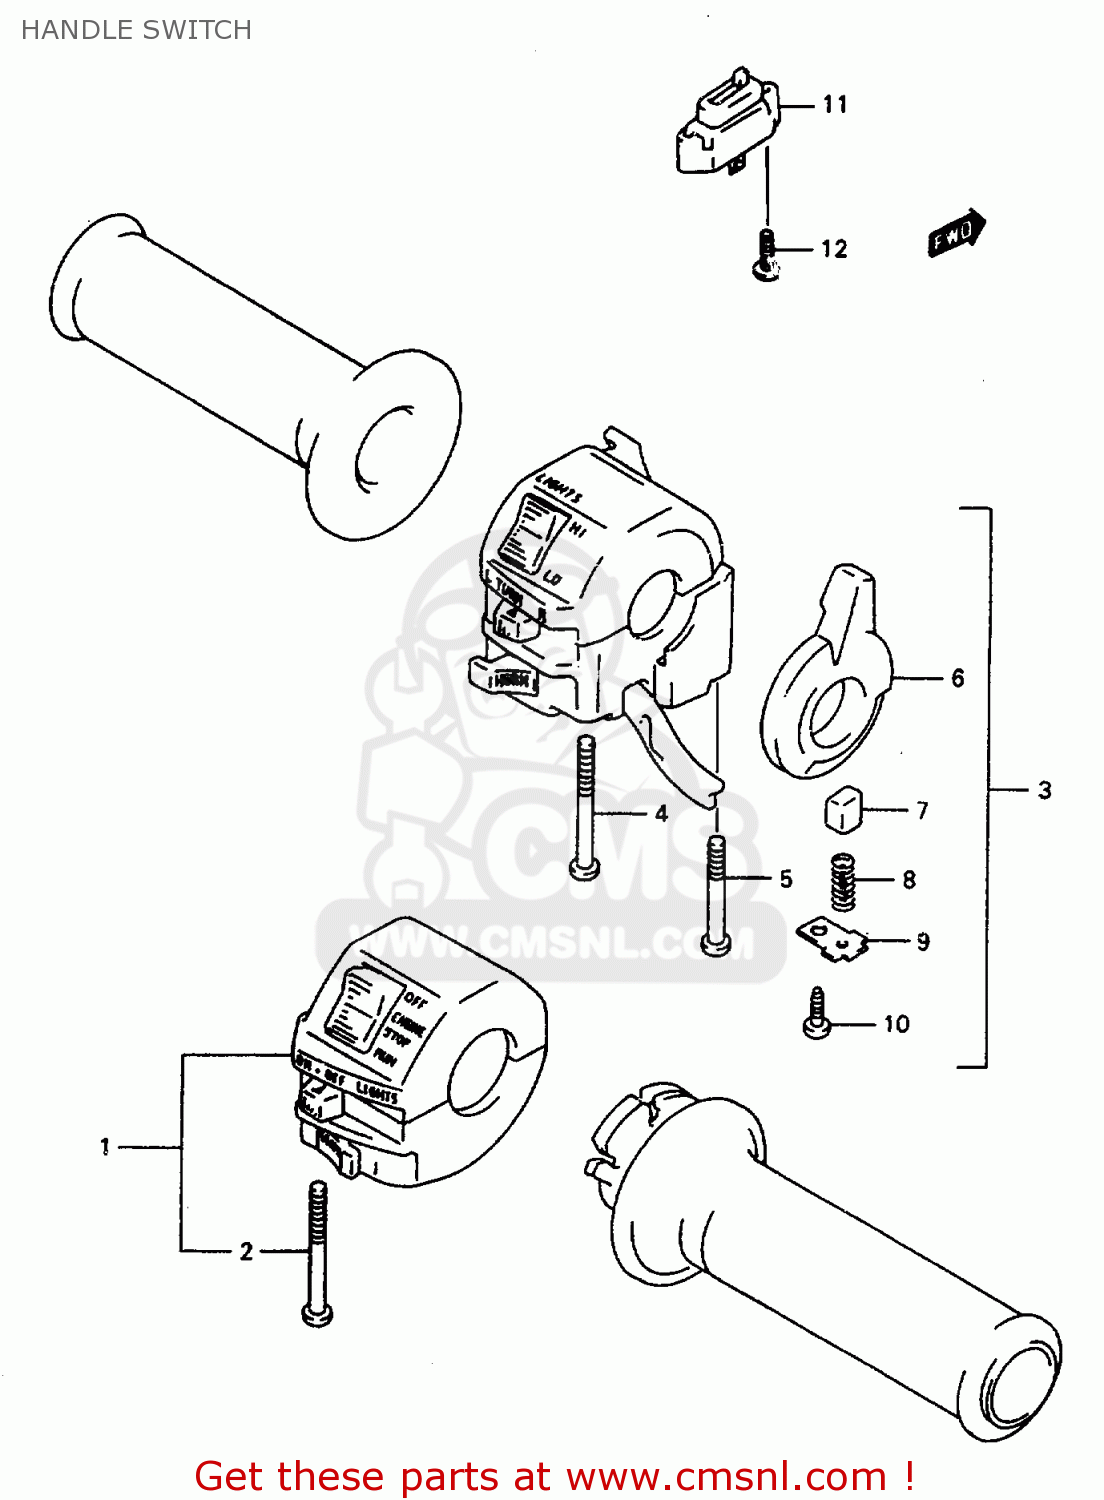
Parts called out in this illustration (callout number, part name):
1	SWITCH, HANDLE
2	SCREW, 5X45
3	SWITCH ASSY
4	SCREW, 5X45
5	SCREW
6	LEVER,CHOKE
7	PIECE,SLIDE
8	SPRING
9	PLATE
10	SCREW, TRUNK BOX
11	SWITCH ASSY,CLUTCH
12	SCREW
